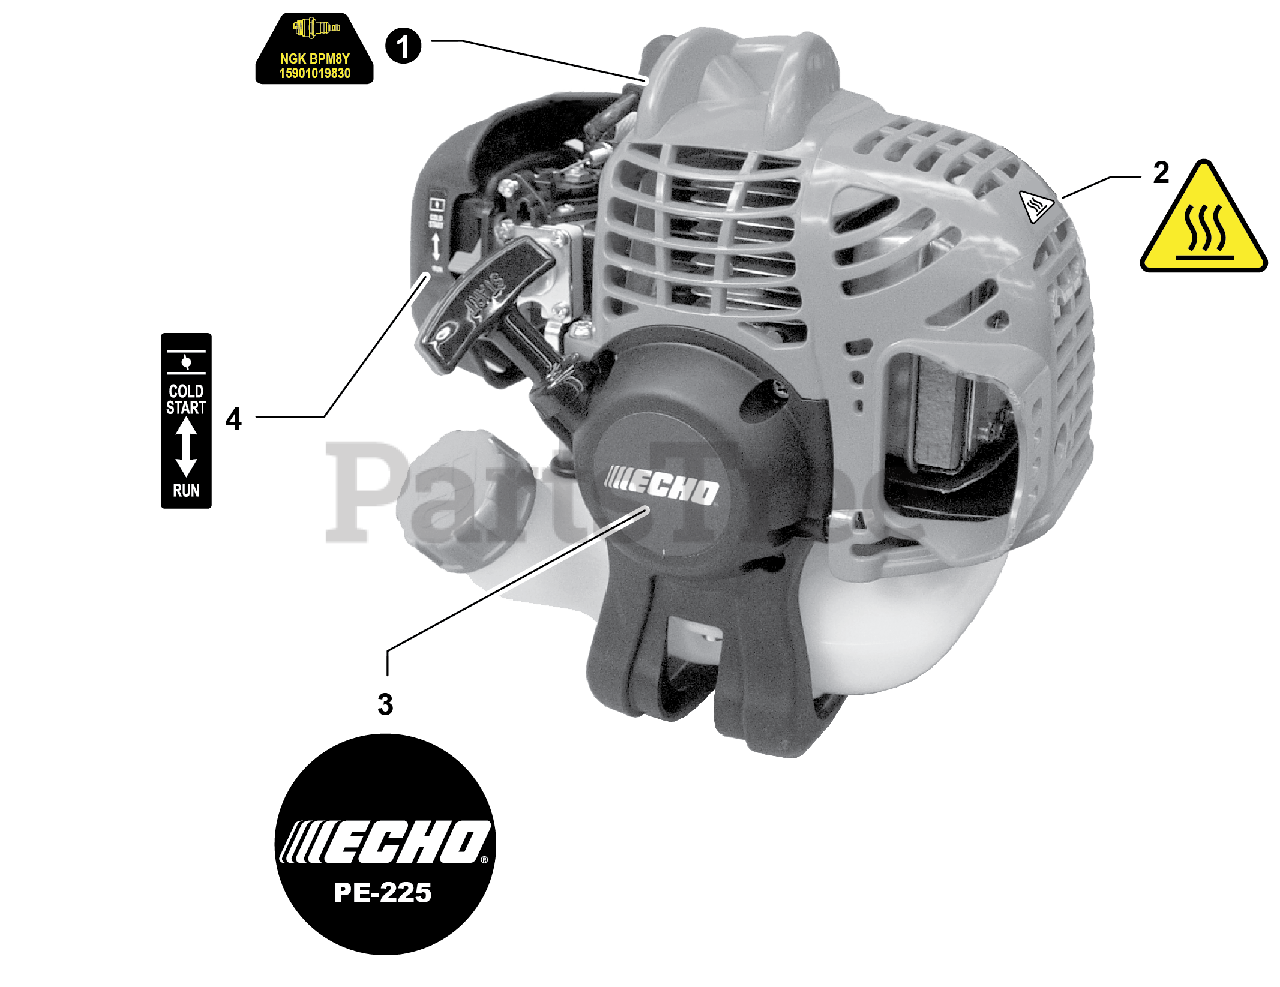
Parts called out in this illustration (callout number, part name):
1	LABEL, SPARK PLUG - BPM8Y
2	LABEL, CAUTION - HOT
3	MODEL LABEL - PE-225
4	LABEL, CHOKE
